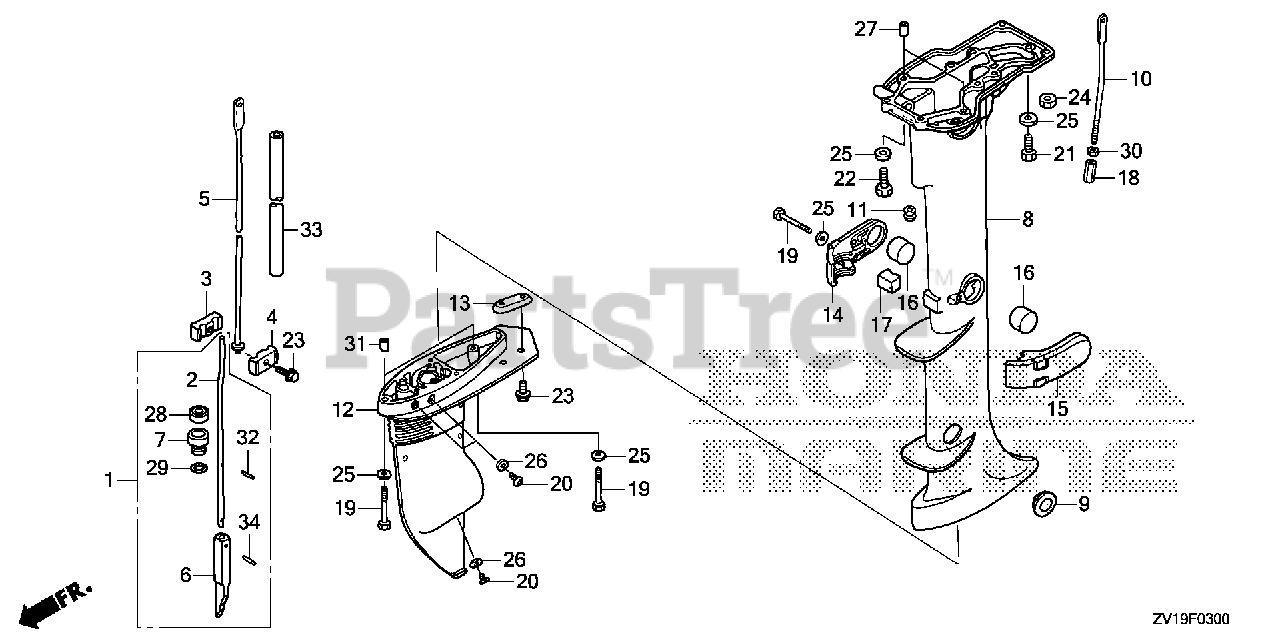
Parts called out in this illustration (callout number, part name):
1	ROD B, SHIFT
2	ROD B, SHIFT
3	JOINT, R. SHIFT ROD
4	JOINT, L. SHIFT ROD
5	ROD A, SHIFT (S)
7	HOLDER, SEAL
8	CASE, EXTENSION *NHB14M* (S) (AQUA MARINE SILVER METALLIC)
9	GROMMET, EXTENSION
10	SHAFT, REVERSE LOCK
11	GROMMET, LOCK SHAFT
12	CASE, GEAR *NHB14M* (AQUA MARINE SILVER METALLIC)
13	METAL, ANODE
14	HOUSING, R. MOUNTING (LOWER) *NHB14M* (AQUA MARINE SILVER METALLIC)
15	HOUSING, L. MOUNTING (LOWER) *NHB14M* (AQUA MARINE SILVER METALLIC)
16	RUBBER A, MOUNTING (LOWER)
17	RUBBER B, MOUNTING (LOWER)
18	NUT, REVERSE LOCK
19	BOLT, HEX. (6X50)
20	BOLT, OIL CHECK (8X8)
21	BOLT, HEX. (6X32)
22	BOLT, HEX. (6X40)
23	BOLT, FLANGE (6X16) (SUS)
24	NUT, HEX. (6MM)
25	WASHER, PLAIN (6MM) Use up to Frame SN 4800342.
26	WASHER, NYLON (8MM)
27	PIN, DOWEL (8X16)
28	SEAL, WATER (6MM)
29	O-RING (10.8X2.4) (ARAI)
30	NUT, HEX. (5MM)
31	PIN A, DOWEL (8X14)
32	PIN, SPRING (2.5X10)
34	ROLLER (2.5X11.8)
